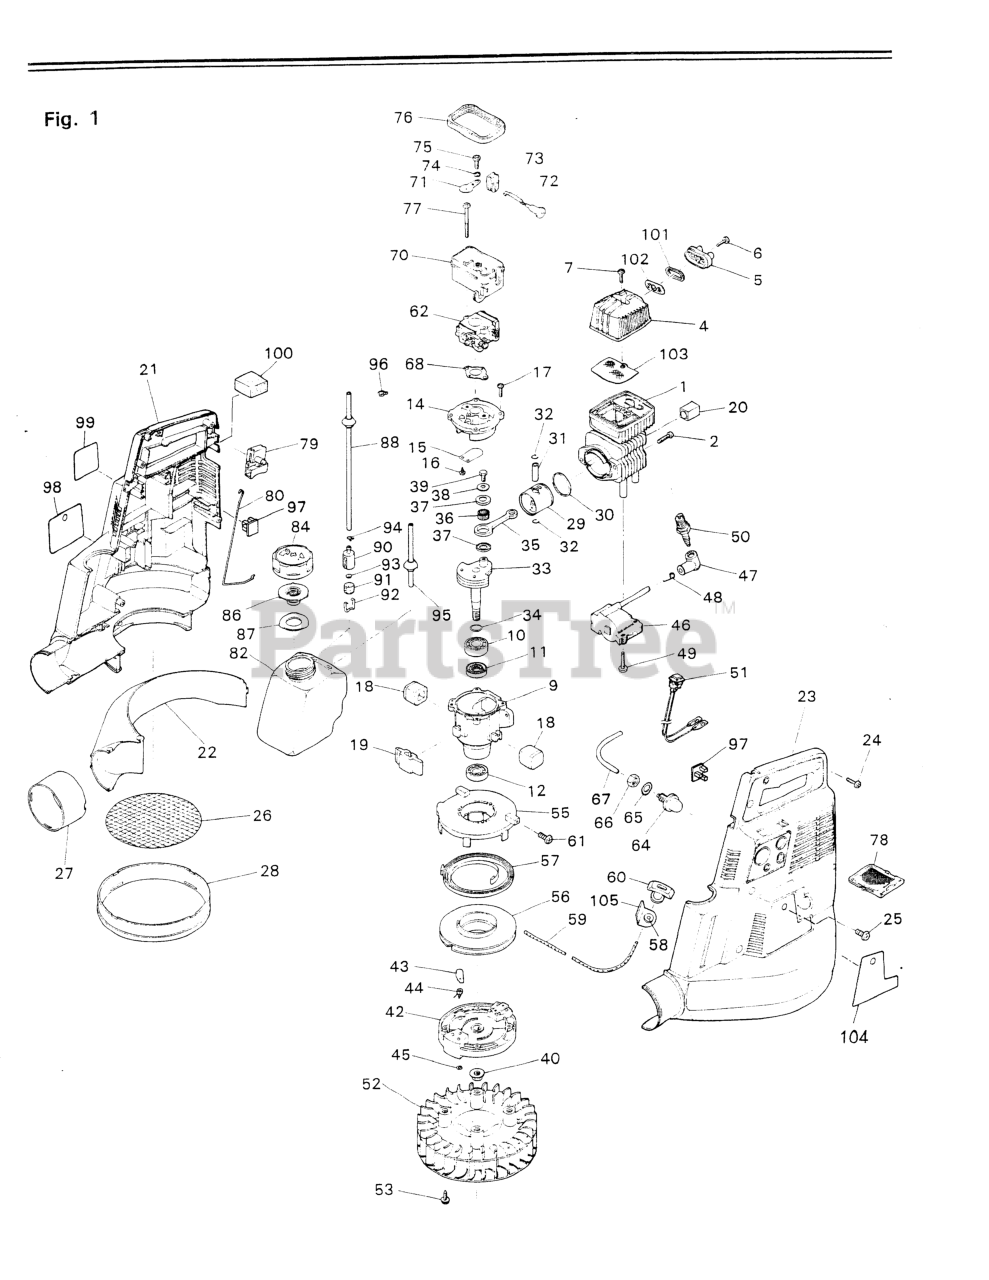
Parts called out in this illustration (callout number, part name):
1	CYLINDER
2	SCREW, M5 X 20
5	TAIL, MUFFLER
6	SCREW, TAIL (NLA)
7	SCREW (RPLS -15210)
11	SEAL, OIL (NO LONGER AVAIL)
14	CASE COVER(NO LONGER AVAILABLE
15	REED VALVE (NO LONGER AVAIL)
17	SCREW, CASE(NO LONGER AVAIL)
18	MOUNT, SIDE(NO LONGER AVAIL)
19	MOUNT, FRONT
20	MOUNT, REAR(NO LONGER AVAIL)
21	HOUSING (R)
23	HOUSING (L)
25	SCREW, MOUNT (NLA)
28	RING (A)
29	PISTON (NO LONGER AVAILABLE)
30	RING, PISTON
31	PIN, PISTON(NOLONG AVAIL)
32	RING, SNAP (RPLS 1101-41320)
33	CRANKSHAFT-C(NOLONG AVAIL)
34	WASHER(NO LONGER AVAILABLE)
38	WASHER (NO LONGER AVAIL)
39	BOLT (NO LONGER AVAILABLE)
40	NUT
42	ROTOR ASSEMBLY (NLA)
43	RATCHET
44	SPRING, RETURN
45	E-RING
46	COIL ASSEMBLY (NLA)
48	SPRING
52	FAN COMP
53	SCREW, FAN (NOLONG AVAIL)
56	PULLEY (NLA)
57	SPRING (NLA)
61	SCREW, M4 X 8
64	BODY ASSY
65	WASHER (NO LONGER AVAIL)
66	NUT, PRIMER (NO LONGER AVAIL)
67	PRIMER HOSE
68	GASKET (NO LONGER AVAILABLE)
71	PLATE (NO LONGER AVAILABLE)
72	ROD, CHOKE
75	SCREW, TAIL (NLA)
77	SCREW, CARB(NOLONG AVAIL)
79	LEVER ASSEMBLY
86	VALVE, VENT
88	LINE, FUEL
90	WEIGHT (NLA)
91	FILTER (NLA)
92	RETAINER (NLA)
93	SCREEN (NLA)
94	CLIP (REPLACES 2841-31280)
95	PIPE (RPLS 1601-85701)
96	CLIP
102	ARRESTER (NO LONGER AVAILABLE)
103	SCREEN (NLA)
104	DECAL (HB260)
105	DEFENCER
NI	MUFFLER ASSEMBLY
NI	CASE COVER(NO LONGER AVAILABLE
NI	ROTOR ASSEMBLY (NLA)
NI	STARTER ASSEMBLY
NI	PUMP ASSY (NO LONGER AVAIL)
NI	CLEANER ASSEMBLY
NI	VALVE COMPLETE
